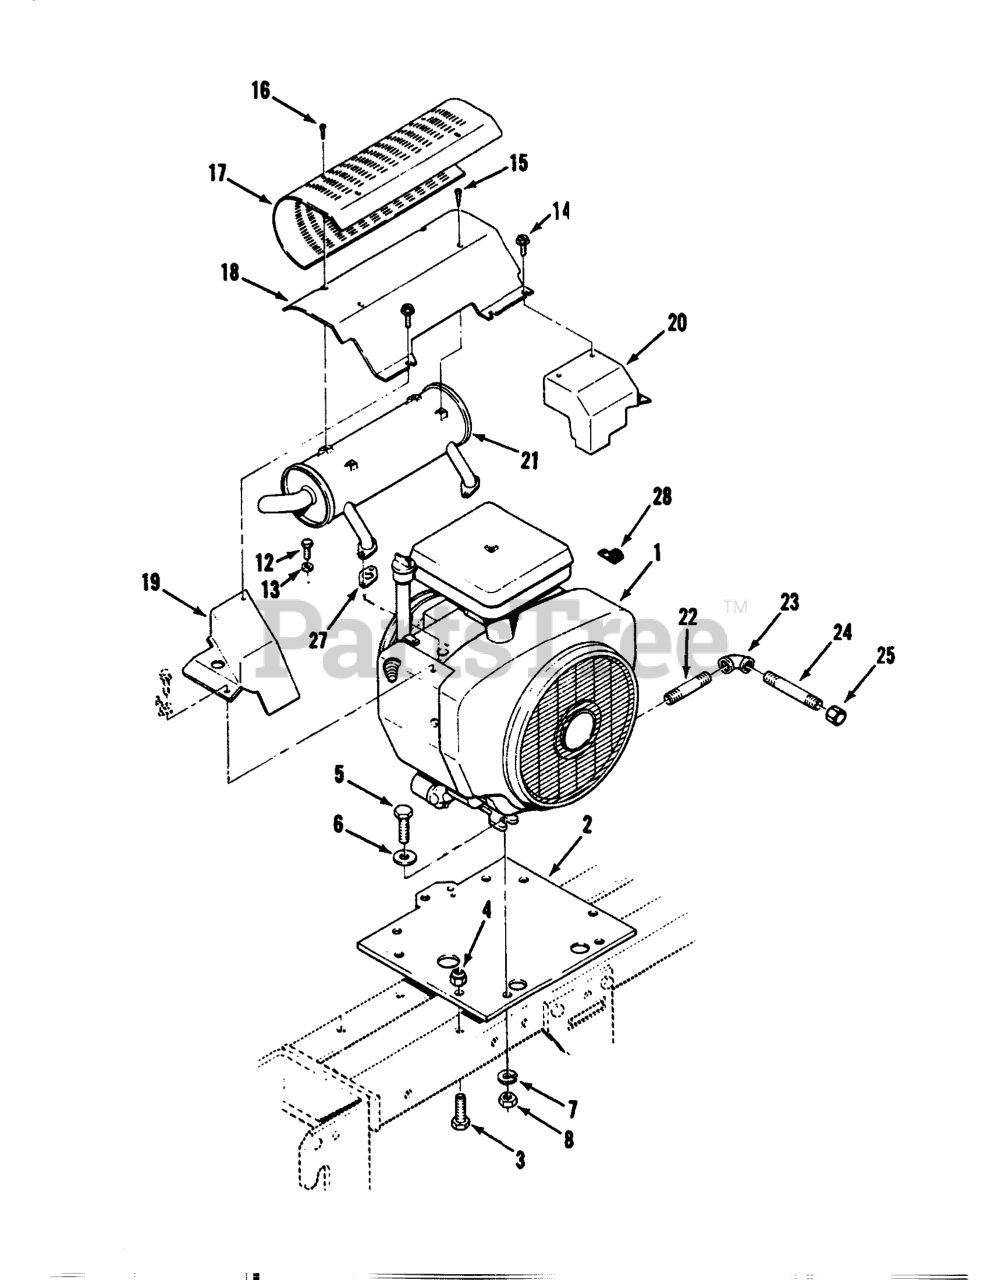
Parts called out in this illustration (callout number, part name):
1	Engine-20HP
2	PLATE-ENGINE B
3	SCREW-HH
4	NUT-LOCK, NI
5	SCREW-HH
6	WASHER-FLAT
7	WASHER-LOCK
8	NUT-HEX
12	SCREW-HH
13	WASHER-LOCK
14	HEX WASHER HD SCREW
15	Screw
16	Screw-Stainless
17	Shield
18	Air Deflector
19	COVER EXHAUST LH
20	COVER EXHAUST RH
21	MUFFLER-EXHAUST
22	NIPPLE-PIPE
23	ELBOW 3/8 90 DEG
24	PIPE-NIPPLE 3/8 X 4"
25	Cap
27	Gasket-Exhaust
28	CLIP
